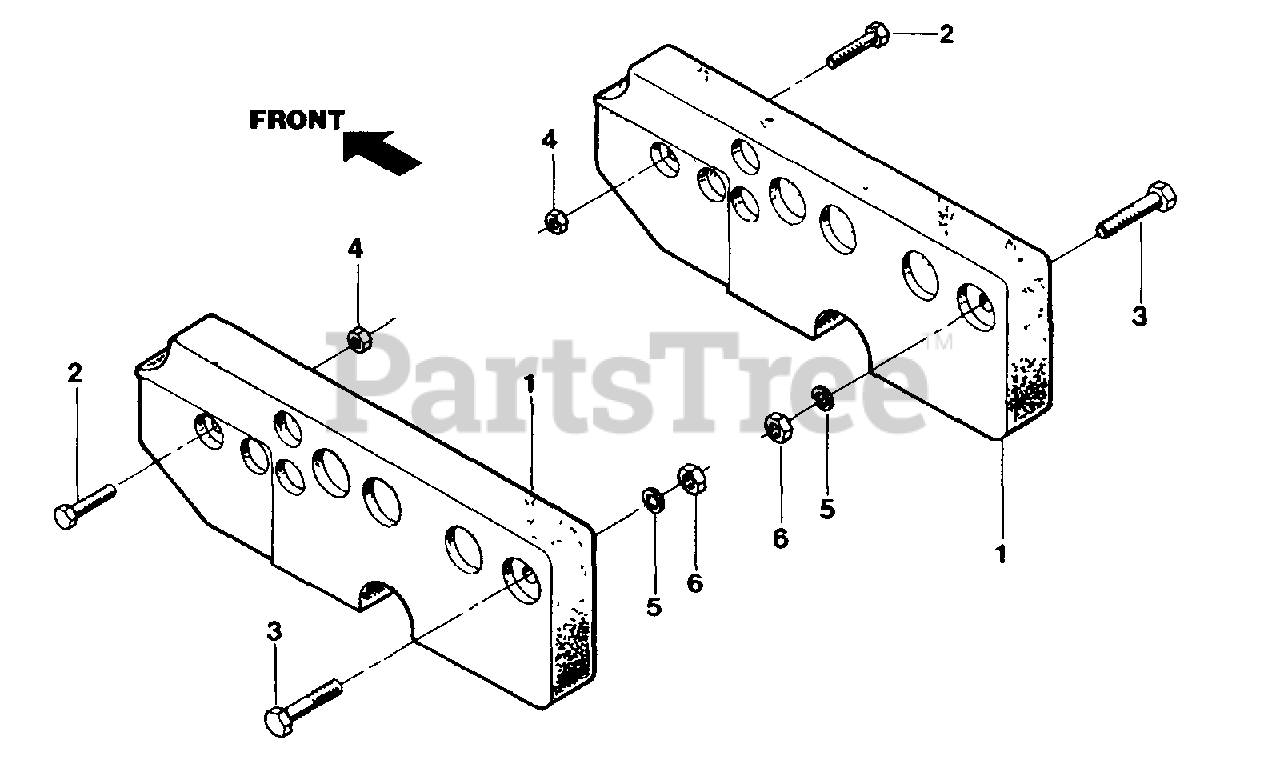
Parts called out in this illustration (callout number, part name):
1	Frame Weight
2	Bolt-Hex Head, 1/4-20 x 1-1/4
3	Bolt-Hex Head, 5/16-18 x 1-1/2
4	Nut, Hex Hd., 1/4-20
5	Lockwasher - 5/16
6	Nut, Hex Hd., 5/16-18
